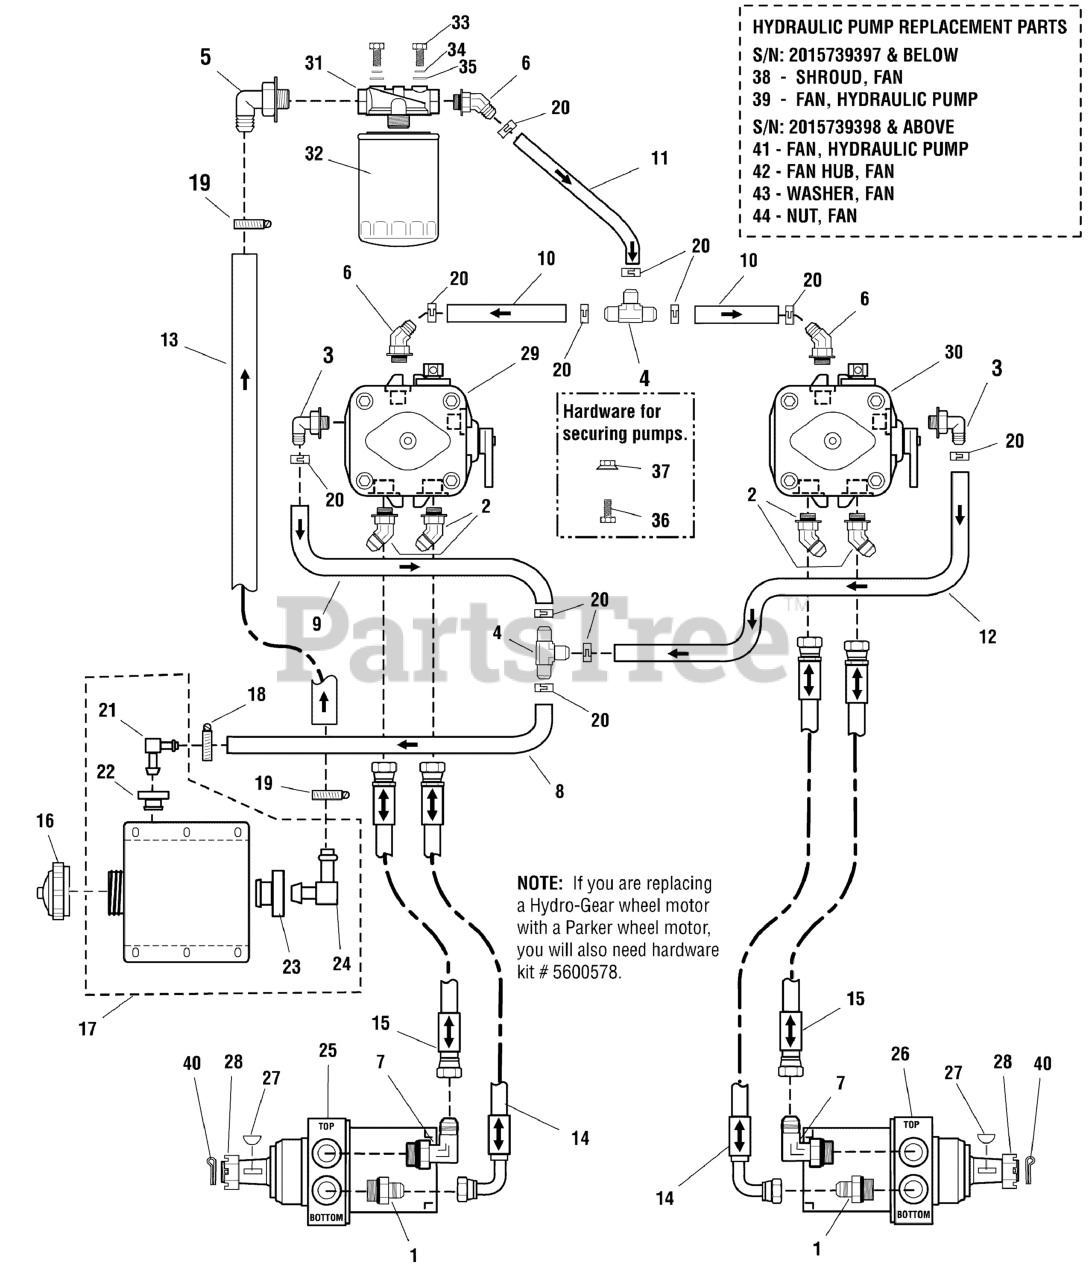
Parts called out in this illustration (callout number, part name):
1	ADAPTER, HYD.
3	ADAPTER, 90 DEG, 9/16-3/8 BARB
4	FITTING, TEE, 1/2 HOSE
5	ADAPTER, 90 DEG, 9/16-5/8 BARB
6	ADAPTER, 45 DEG, 9/16-3/8 BARB
7	FITTING, #10 ORING-#8 JIC, 90D
8	HOSE, 3/8" PUSH-LOCK, 22.00"
9	HOSE, 3/8" PUSH-LOCK, 6.50"
10	HOSE, 3/8" PUSH-LOCK, 6.00"
11	HOSE, 3/8" PUSH-LOCK, 8.00"
12	HOSE, 3/8" PUSH-LOCK, 23.00"
13	HOSE, 5/8" PUSH-LOCK, 23.50"
16	CAP, HYDRAULIC
17	TANK, HYDRAULIC, ASSEMBLY
18	CLAMP, #4 HOSE, STAINLESS
19	CLAMP, #10 HOSE, STAINLESS
20	CLAMP, HOSE
21	FITTING, ELBOW, 3/8"
22	BUSHING-FUEL TANK RED RUBBER
23	GROMMET
24	FITTING, ELBOW, 5/8"
27	KEY
28	NUT, CASTLE, 1-20
31	FILTER HEAD, HYDRAULIC
32	FILTER, OIL
33	BOLT, 1/4"-20 X 3/4" GD5 YZ
34	WASHER, 1/4 SAE
35	WASHER, 1/4 LOCK
36	BOLT, 3/8-16 X 1-1/4" GD5 CZ
37	NUT, 3/8-16 HEX SERRATED FLANGE
38	SHROUD, FAN
39	FAN, HYD. PUMP
40	PIN, COTTER, 1/8' X 2"
41	FAN, 8.31", 16CC HYDRO-GEAR PUMP
42	FAN HUB, 16CC PUMP
43	WASHER, 16CC PUMP
44	LOCK NUT,NLYON INSERT 5/16-24,GRD8, 5010
